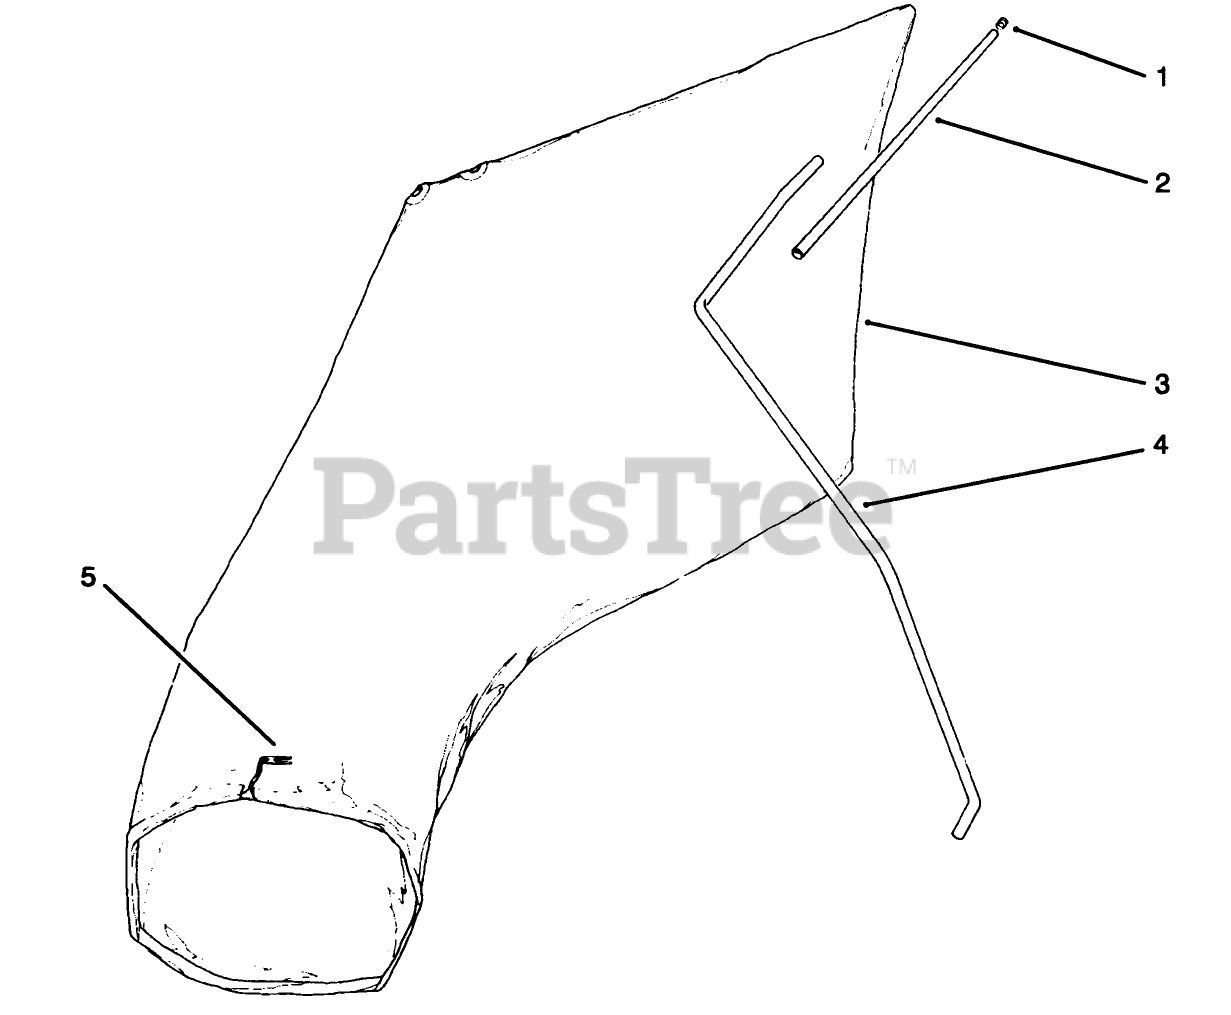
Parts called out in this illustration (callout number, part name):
2	BAG HANGER TUBE
4	HANGER ROD
5	BAG CORD FASTENER
